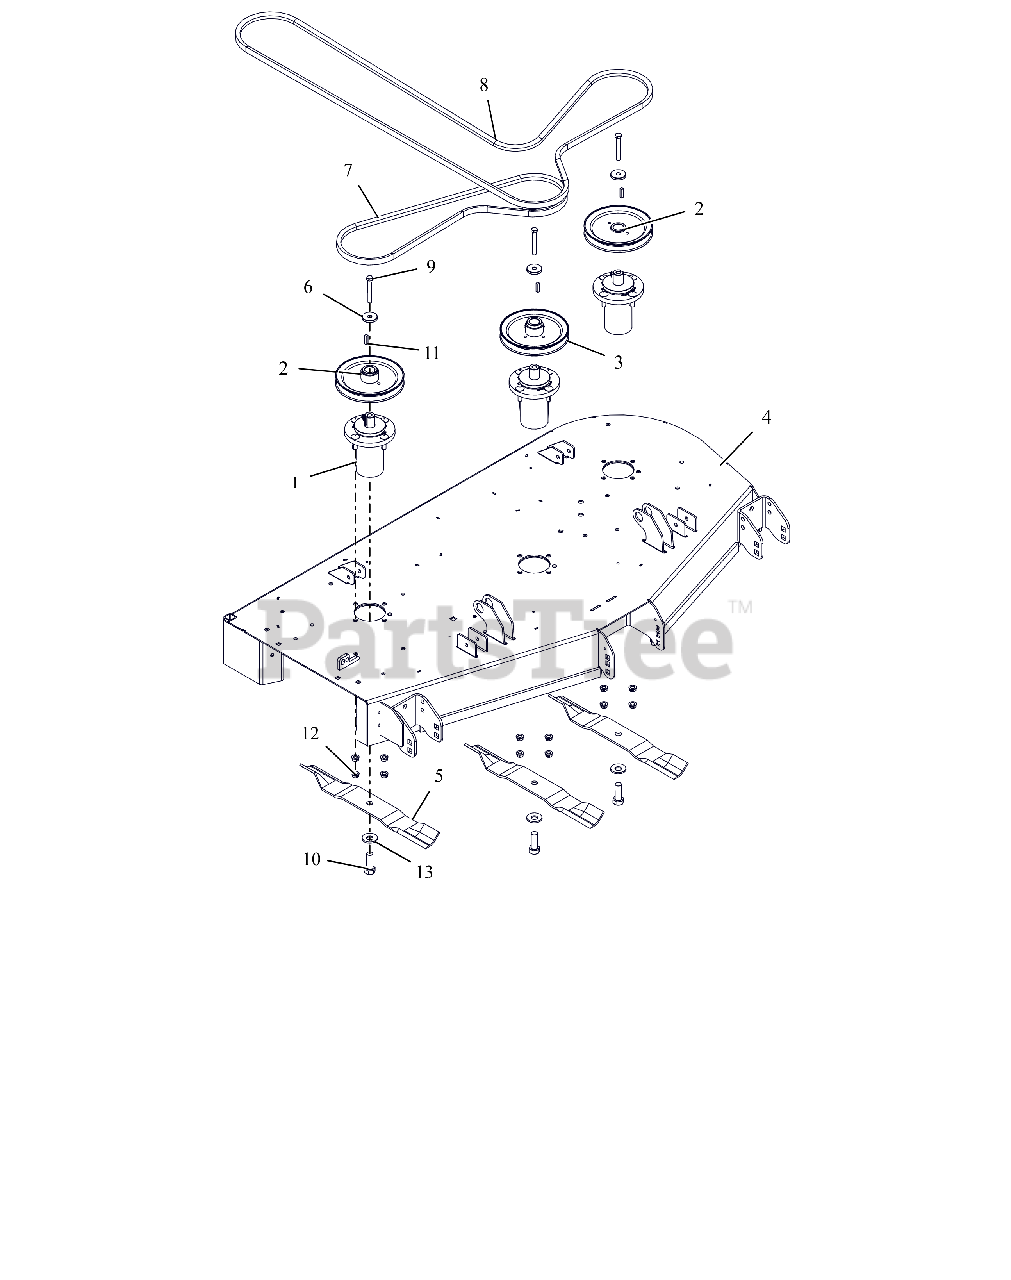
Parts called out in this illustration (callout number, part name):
1	ASM, MAINT FREE ALUM SPINDLE
2	PULLEY, V-1" ID X 6.75" OD
3	PULLEY, DOUBLE-1"ID X 6.75"OD
4	KIT,DECK-52" W/DECALS-ARIENSCE
5	BLADE, 18"
6	RETAINER, SHEAVE
7	V-BELT, B-COGGED
8	V-BELT, HB SECTION
9	BLT-HEX .38-16X2.75 GR8 YWZC
10	BLT-HEX .62-18X1.75 GR8 YWZC
11	KEY, SQ .25X.25X1.00 RC 40-50
12	NUT-LK-CTR-FLG .38-16 YWZC
13	WSHR-BLVL .669X1.535X.138
